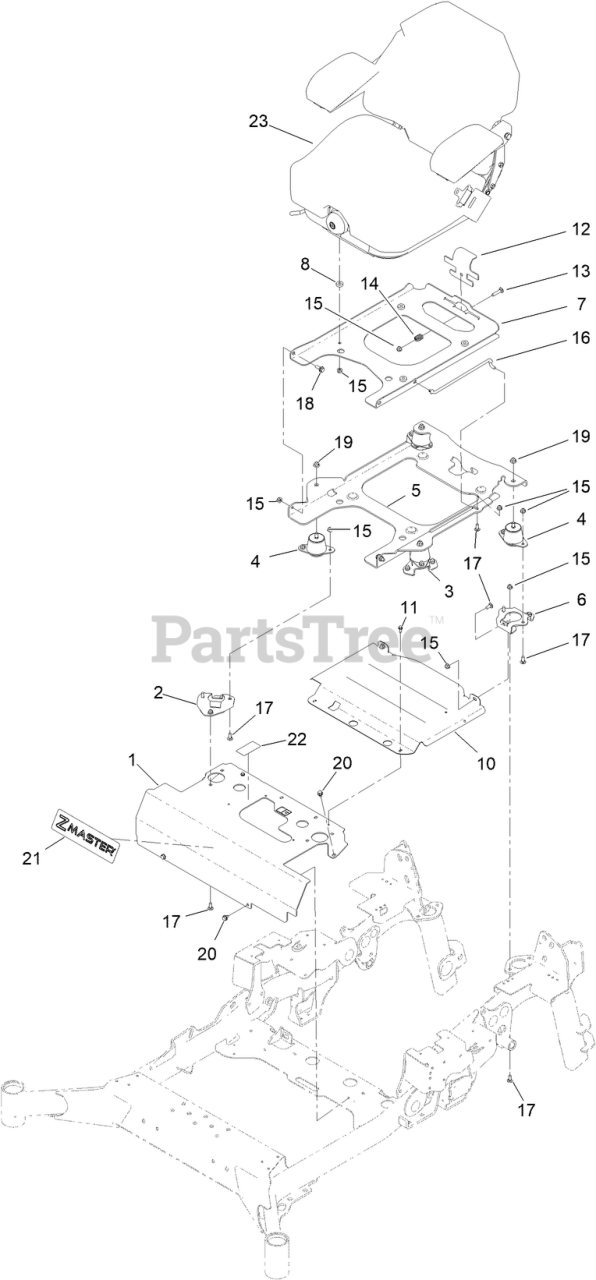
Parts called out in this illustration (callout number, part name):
1	MOUNT-SEAT W/DECALS
2	RISER-SEAT MOUNT, R
3	RISER-SEAT MOUNT, L
4	ISOLATOR-SEAT
5	PLATE,TILT SEAT SUPPORT
6	RISER-SEAT MOUNT, REAR
7	PLATE-FRAME, SEAT
10	HEAT SHIELD - SEAT
11	SCREW-HWH
12	PLATE, SEAT LATCH
13	BOLT-CARR
14	SPRING-COMPRESSION
15	NUT-HF, NI
16	ROD-PROP
17	SCREW-CARR
18	SCREW-SHOULDER
19	NUT-HF, NI
20	SCREW
21	DECAL-CONSOLE
22	DECAL-FLUID, TRANSMISSION
23	ASM-SUSPENSION SEAT, TORO
